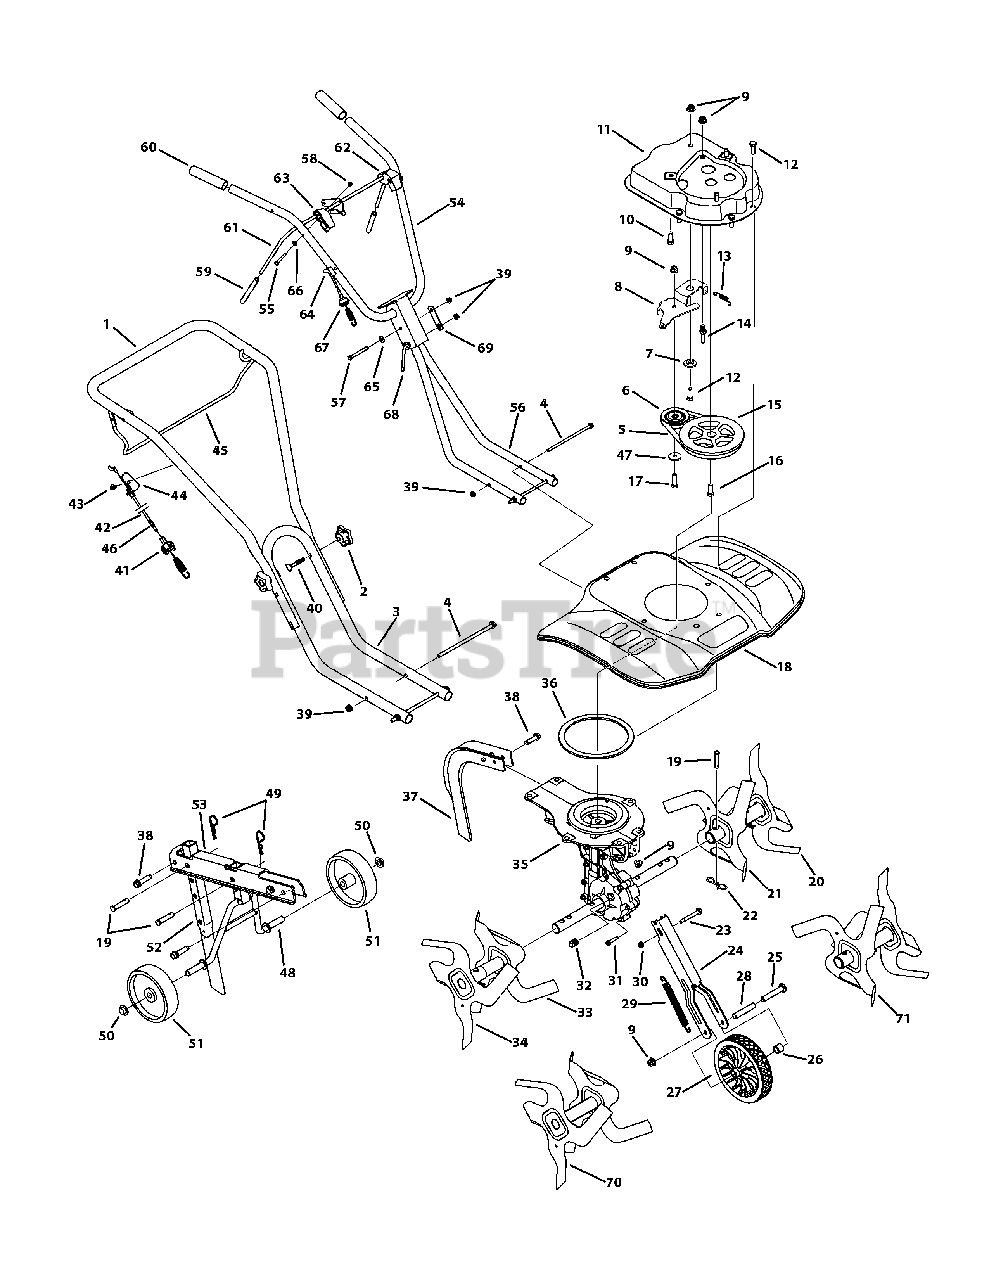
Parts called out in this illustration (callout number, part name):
1	Upper Handle
2	Star Handle Knob
3	Lower Handle
4	Flange Screw: 5/16-18:7.5:GR5
5	V-Belt
6	Idler Pulley
7	Shoulder Spacer
8	Idler Bracket
9	Flange Lock Nut: 3/8-16
10	TT Screw: 3/8-16:1.00
11	Belt Cover - Red
11	Belt Cover - Green
12	Hex Cap Screw: 3/8-16:1.00
13	Extension Spring
14	Stud: 33 x 1.5: 3/8-16
15	Flywheel Pulley
16	Hex Cap Screw: 3/8-24:1.00
17	Hex Cap Screw: 3/8-16:1.55
18	Tine Shield 61 cm - Red
18	Tine Shield 61 cm - Green
18	Tine Shield 40 cm - Red (model 220)
19	Clevis Pin
20	Outer Tine Assembly LH
21	Inner Tine Assembly LH
22	Cotter Pin, Bow Tie
23	Shoulder Screw: .31x2:1/4-20
25	Hex Cap Screw: 3/8-16:3.00
26	Spacer
27	Wheel 7x1.5 Star-Diam
28	Sleeve
29	Extension Spring
30	Flange Lock Nut: 1/4-20
31	TT Screw: 1/4-20:1.25
32	Pipe Plug: 3/8 NPT
33	Inner Tine Assembly RH
34	Outer Tine Assembly RH
35	Case Assembly
35	Case Assembly 40cm (model 220)
36	Gasket
37	Depth Stake Assembly - Black
37	Depth Stake Assembly - Green
38	TT Screw: 3/8-16:1.50
39	Flange Lock Nut: 5/16-18
40	Carriage Bolt
41	Clutch Cable Fitting
42	Clutch Cable
43	TT Screw: 1/4-20:.50
44	Cable Mount Bracket - Black
44	Cable Mount Bracket - Green
45	Clutch Bail - Red
45	Clutch Bail - Green
46	Retaining Ring
47	Flat Washer, .406 x .875 x .059
48	Rear Wheel Tube Assembly
49	Cotter Pin
50	Push Cap
51	Wheel 5 x 1.38
52	Depth Stake Tube
53	Wheel Bracket
54	Upper Handle - Red
54	Upper Handle - Green
55	Hex Head Cap Screw, 1/4-20 x 1.75
56	Lower Handle - Red
57	Hex Head Cap Screw, 5/16-18 x 3.00
58	Hex Lock Nut, 1/4-20
59	Handle Grip
60	Grip, 1.0 ID x 5.0 LG
61	Clutch Bail - Red
61	Clutch Bail - Green
62	Bail Holder LH
63	Bail Holder RH
64	Handle Fitting
65	Bell Washer, .340 x .872 x .060
66	Flat Washer, .25 x .630 x .0515
67	Clutch Cable
68	Handle Crank
69	Retainer Bracket
70	Tine Assembly RH (model 220)
71	Tine Assembly LH (model 220)
